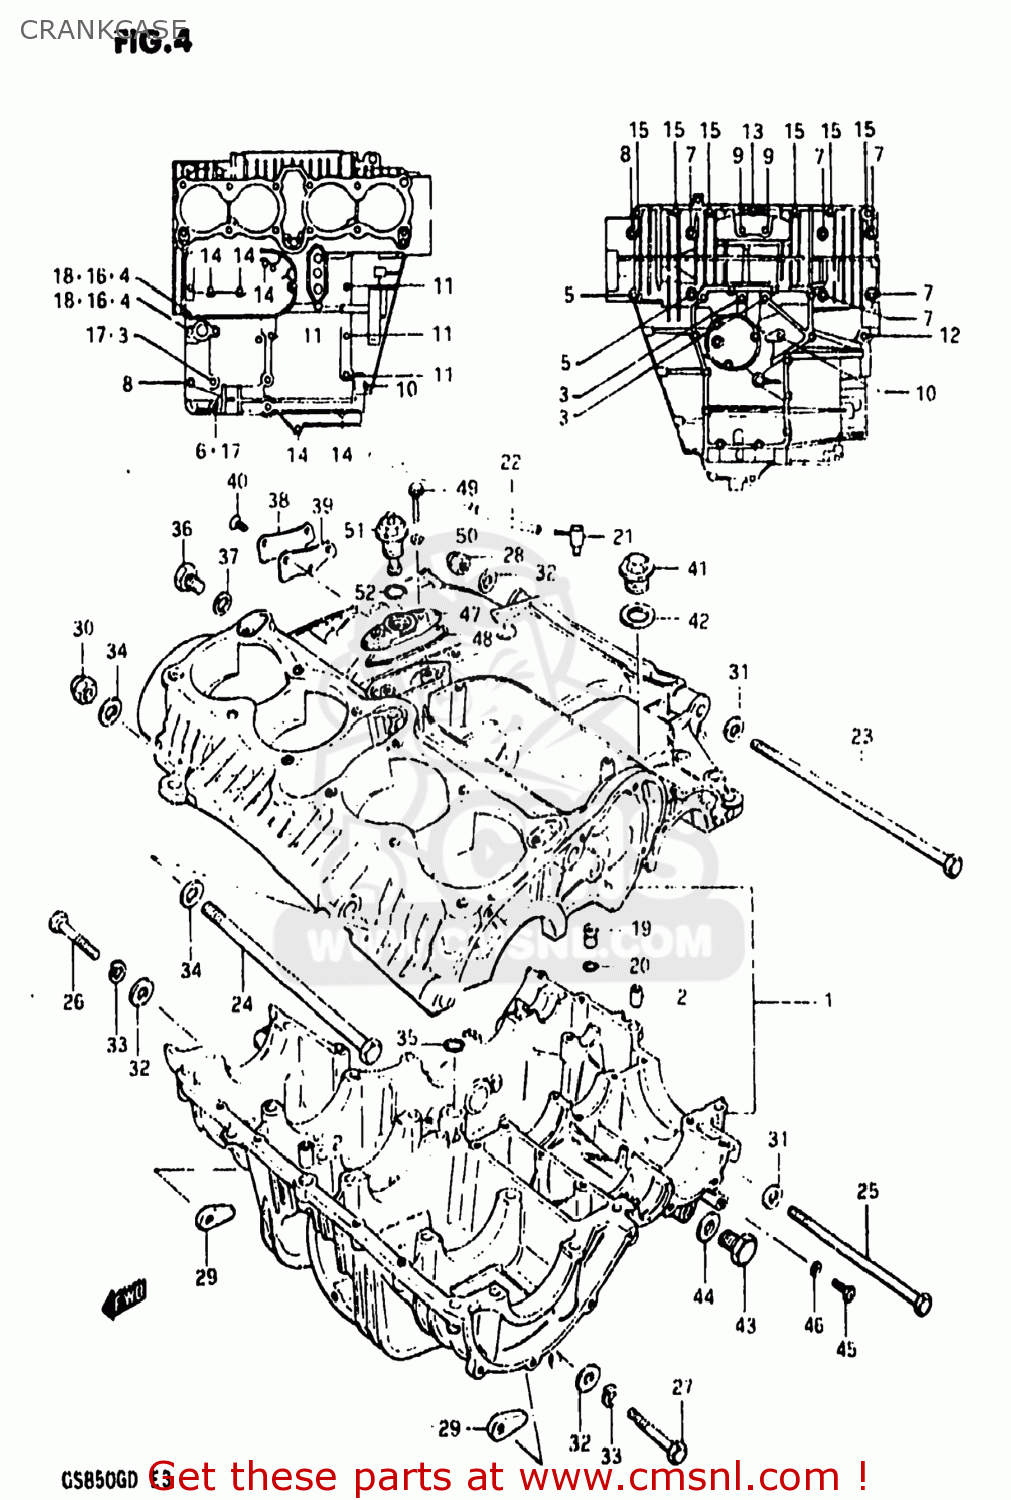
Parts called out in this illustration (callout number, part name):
1	CRANKCASE SET
2	PIN
3	BOLT
4	BOLT
5	BOLT
6	BOLT
7	BOLT 8X90
8	BOLT 8X65
9	BOLT
10	BOLT (6X90)
11	BOLT (6X75)
12	BOLT
13	BOLT ,6X50
14	BOLT,UNDER
15	BOLT 6X35
16	NUT
17	NUT
18	GASKET 8.2X14X1 (NAS)
19	UNION
20	O RING(D:1.05,ID:3.1)
21	BPLUG,BEVEL GEAR BREATHER
22	HOSE
23	BOLT 10X270
24	SHAFT,REAR SWING ARM
25	BOLT(10X165)
26	BOLT 10X60
27	BOLT (10X50)
28	NUT
29	NUT
30	NUT 12MM
31	WASHER(10.5X20X3.2)
32	WASHER
33	LOCK WASHER
34	WASHER
35	O RING(D:3.2,ID:12.9)
36	PLUG (14X12)
37	GASKET(14X19.2X2) (NAS)
38	CAP,OIL GALLERY
39	GASKET,OIL GALLERY (MCA)
40	SCREW
41	PLUG
42	GASKET
43	PLUG
44	GASKET(14X19.2X2) (NAS)
45	SCREW(6X10)
46	GASKET (NAS)
47	HOUSING,OIL PRESSURE SWITCH
48	O RING,PRESSURE SWITCH HOUSING
49	BOLT
50	GASKET (NAS)
51	SWITCH ASSEMBLY
52	O RING(D:1.9,ID:18.8)
